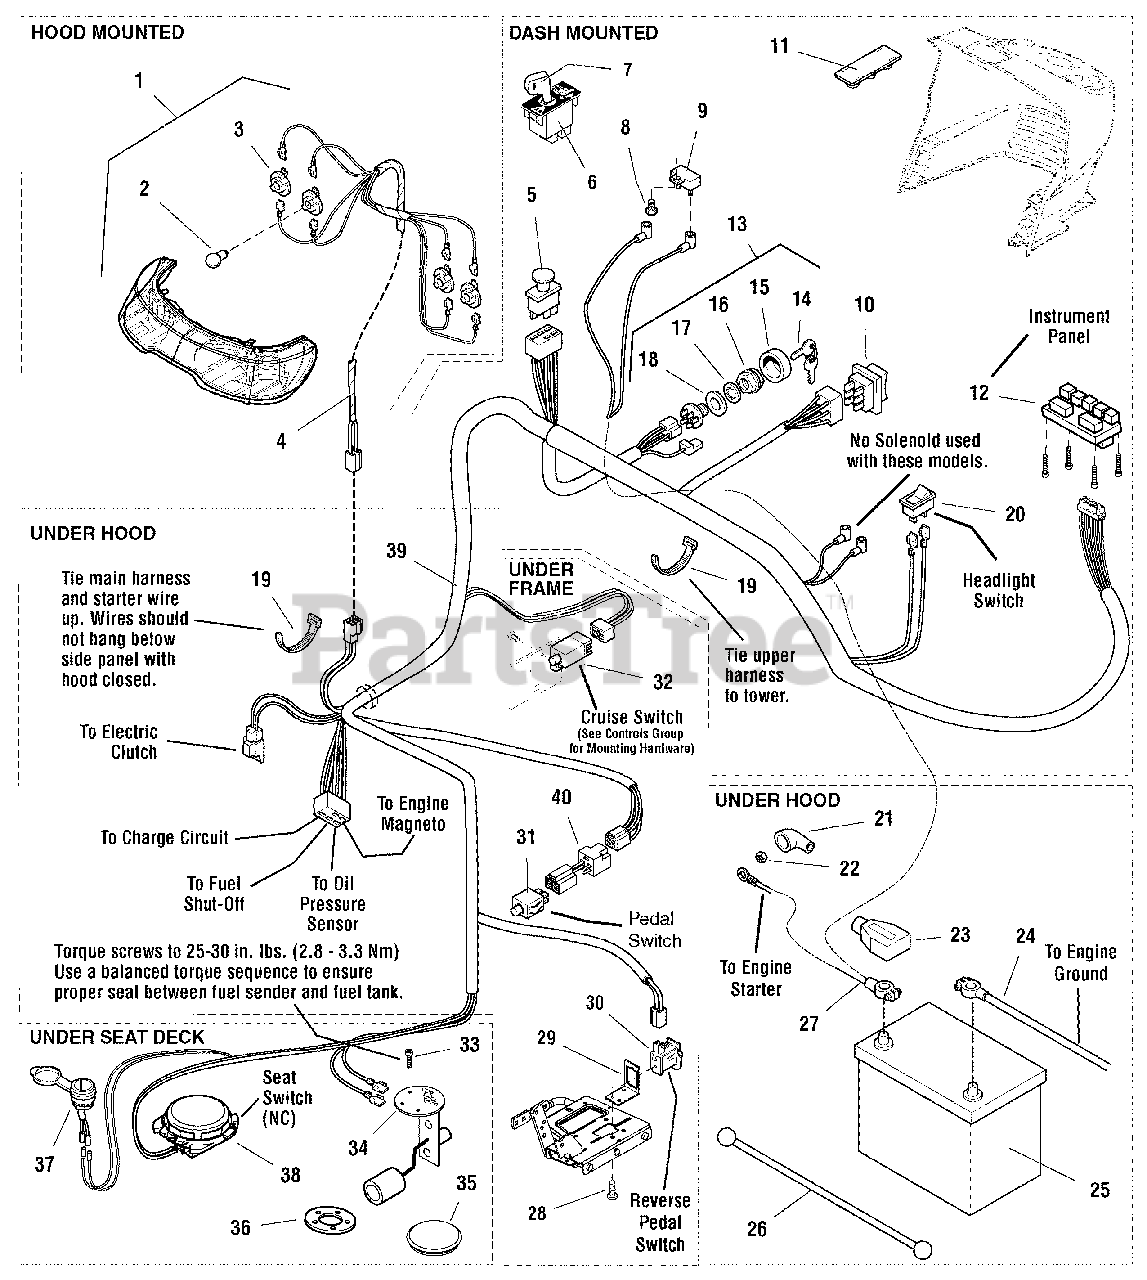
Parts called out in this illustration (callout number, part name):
1	HEADLIGHT ASSEMBLY, 4 Bulb
2	BULB, Headlight, 12.8V
3	SOCKET ASSEMBLY, Headlight, Sealed
4	HARNESS, Headlight
5	SWITCH, PTO Push
6	SWITCH, RMO Module Only
7	KEY, RMO Module, Plastic
8	CAPSCREW, Hex Washer Head Taptite 1/4-20 x 1/2
9	BREAKER, Circuit
10	SWITCH, Electric Lift Rocky
12	PANEL, Instrument w/Fuel Gage
13	SWITCH ASSEMBLY, Ignition
14	KEY, Ignition
15	COVER, Switch
16	NUT, Hex Flange 5/8-32 Ignition Switch Die Cast
17	LOCKWASHER, Interal Tooth 5/8
18	WASHER, 5/8
19	TIE, Self Locking
20	SWITCH, Headlight
21	COVER, Terminal Red
22	NUT, Hex Flange
23	INSULATOR, Battery
25	BATTERY, 12 Volt, 6 Cell, 500 Amps CCA
28	SCREW, Hex Washer Head Taptite, 1/4-20 x 3/8
29	BRACKET, Switch Mounting
30	SWITCH, Push Button, Reverse Pedal
31	SWITCH, Push Button, Foot Pedal
32	SWITCH, Cruise Control
33	SCREW, Pan Head Torx #10-32 x 1/2
34	SENDER, Fuel Tank
37	OUTLET, 12 Volt
38	SWITCH, Operator Present, Seat
39	HARNESS, Wiring w/12 Volt
39	HARNESS, Wiring w/12 Volt & Electric HOC
40	WIRING ASSEMBLY, All Conditions Shutdown
